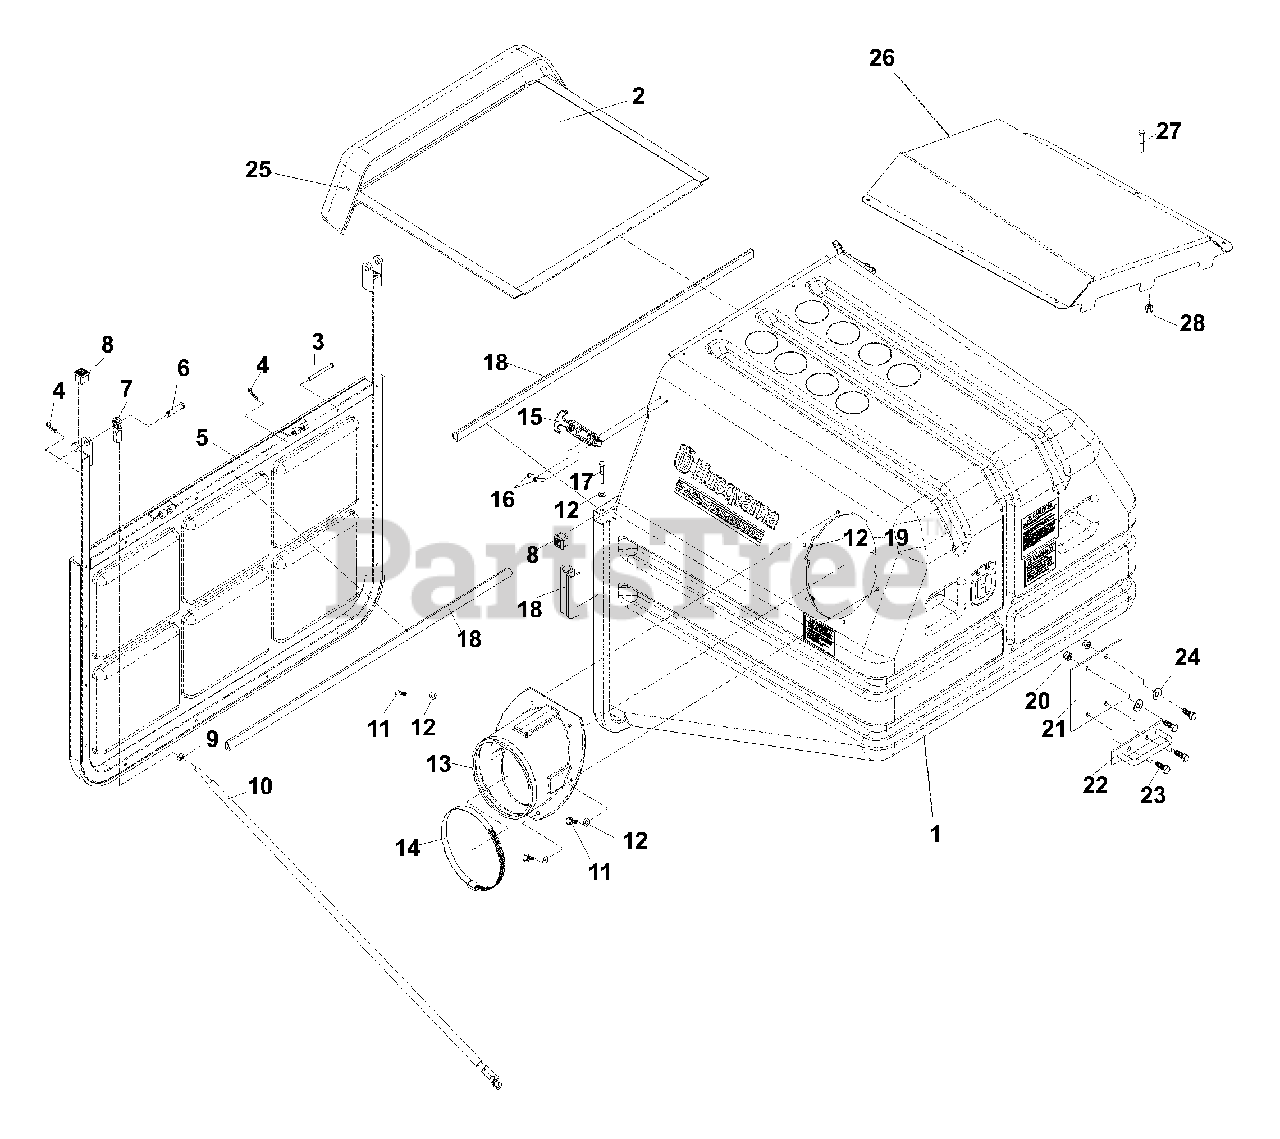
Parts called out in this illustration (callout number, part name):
2	EXHAUST ASM.
3	CLEVIS PIN, 1/4 X 2 3/4
4	HAIR PIN, #13
6	CLEVIS PIN, 3/8 X 1 3/4
7	ROD END
9	NUT, 3/8-24
10	ARM
11	BOLT, 1/4-28 X 1
12	WASHER, 1/4
14	HOSE CLAMP
16	SCREW, 10-24 X 1 1/4, P.T.H.
17	BOLT, 1/4-20 X 2
18	DOOR SEAL KIT (CONTAINS 3 SEALS)
19	NUT, 1/4-20, NYLOC
20	NUT, 3/8-16, NYLOC
21	BACK PLATE
22	LATCH
23	BOLT, 3/8-16 X 1
24	WASHER, 3/8
25	LATCH BASE
27	SCREW #10-24 X 3/4 STD RD
28	NUT #10-24, NYLOC
